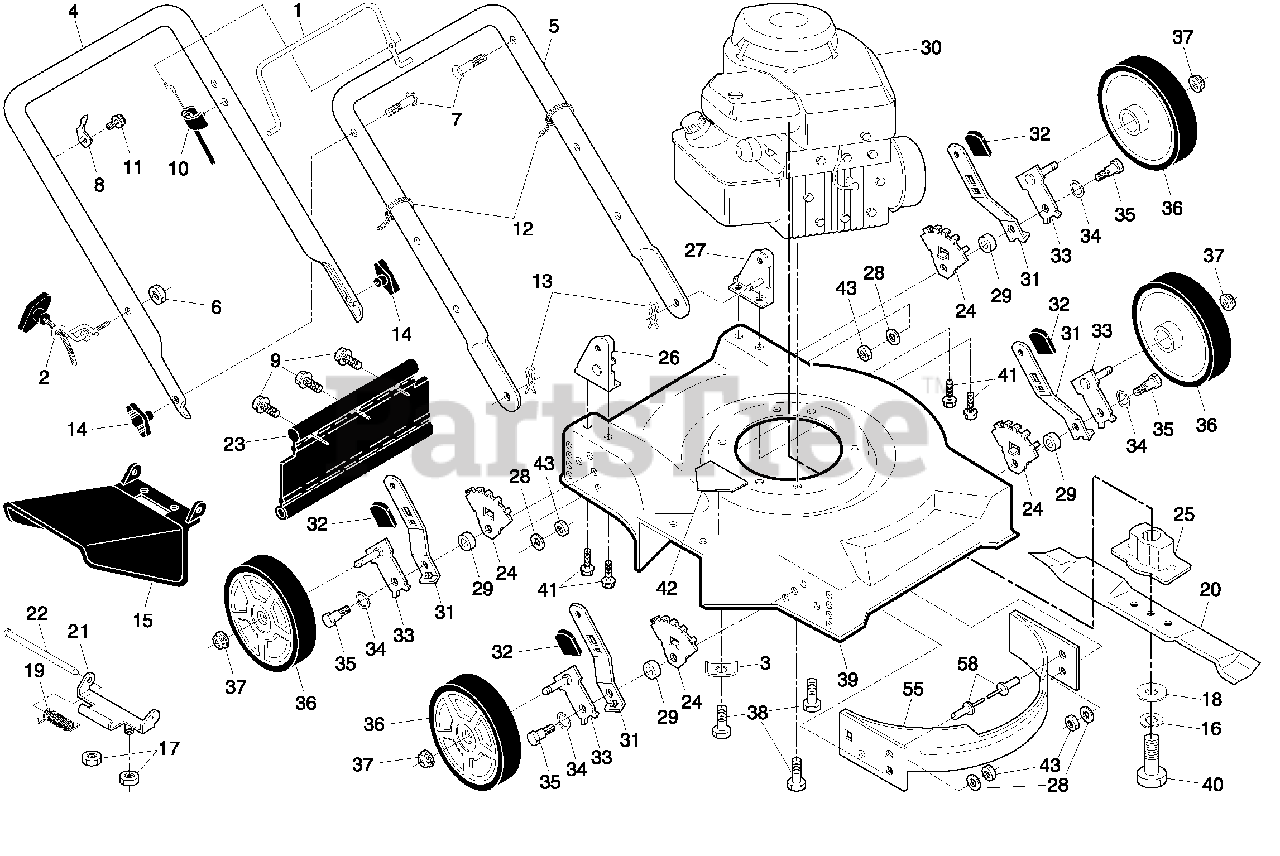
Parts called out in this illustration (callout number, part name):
1	Control Bar
2	Rope Guide
4	Upper Handle
5	Lower Handle
7	Handle Bolt 5/16-18 x 1-3/4
8	Up-Stop Bracket
9	Hex Washer Head Screw #10-24 x 1/2
10	Engine Zone Control Cable
11	Screw
12	Wire Tie
13	Hairpin Cotter
14	Knob, Handle
15	Discharge Guard
16	Helical Lock Washer 3/8
17	Locknut, Hex 1/4-20
18	Hardened Washer
19	Torsion Spring
20	Blade, 20"
21	Hinge Deflector
22	Hinge Rod
23	Rear Deflector
24	Wheel Adjusting Bracket
25	Blade Adapter
26	Handle Bracket Assembly, RH
27	Handle Bracket Assembly, LH
28	Washer, Flat
29	Spacer
31	Selector Spring
32	Selector Knob
33	Axle Arm Assembly
34	Washer, Curved, Cylindrical
35	Shoulder Bolt
36	Wheel and Tire Assembly
37	Nut, Hex
38	Hex Head Thread Rolling Screw 3/8-16 x 1-1/8
39	Lawn Mower Housing
40	Hex Head Screw 3/8-24 x 1-3/8 Grade 8
41	Thread Cutting Screw 5/16-18 x 3/4
42	Danger Decal
43	Locknut, Hex 3/8-16
55	Baffl e, Front
58	Pop Rivet
58	Operator’s Manual, English
58	Operator's Manual, Spanish
58	Repair Parts Manual, English
